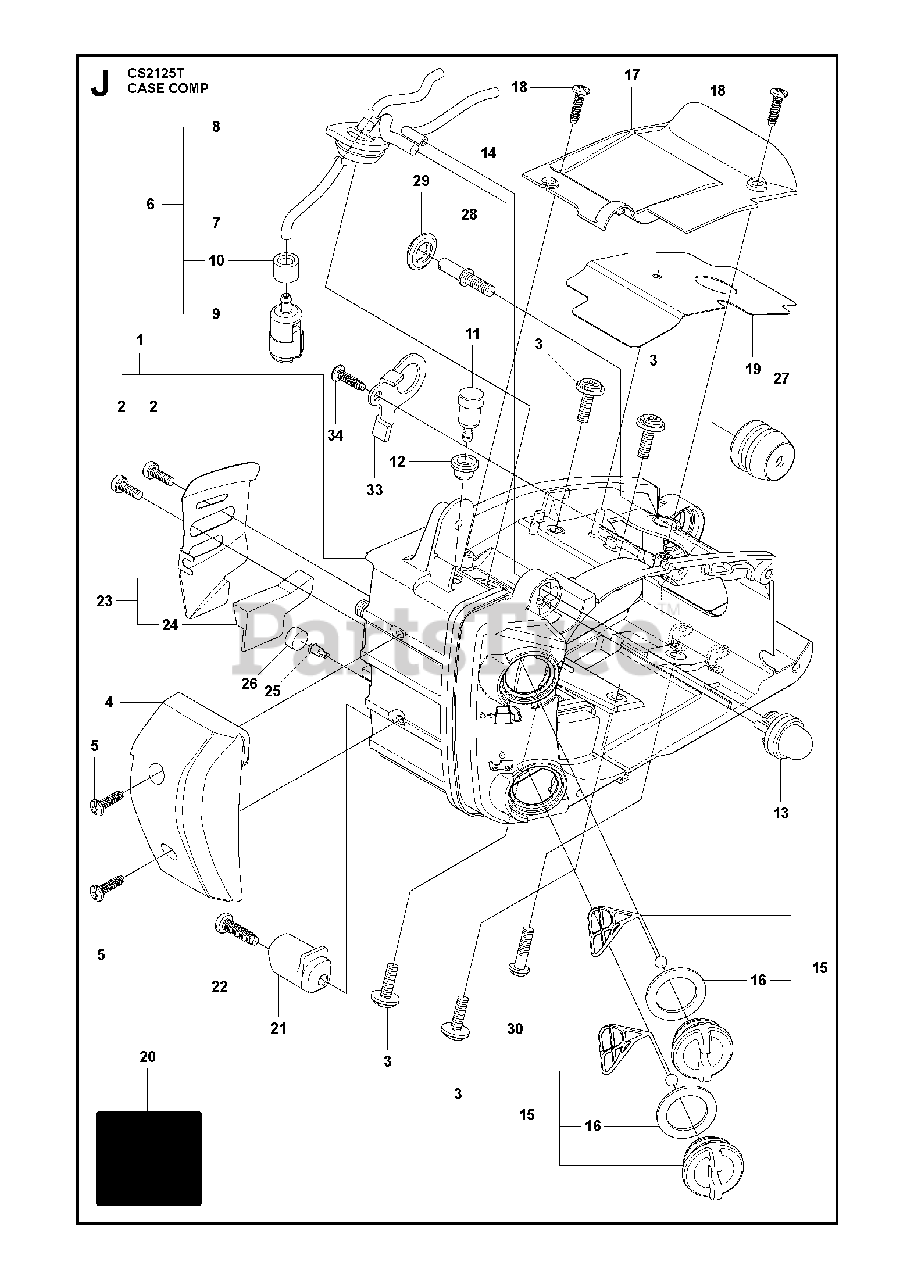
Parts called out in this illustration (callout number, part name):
10	COLLER
11	BREATHER
12	GROMMET
16	GASKET
28	BOLT
33	HANGER
